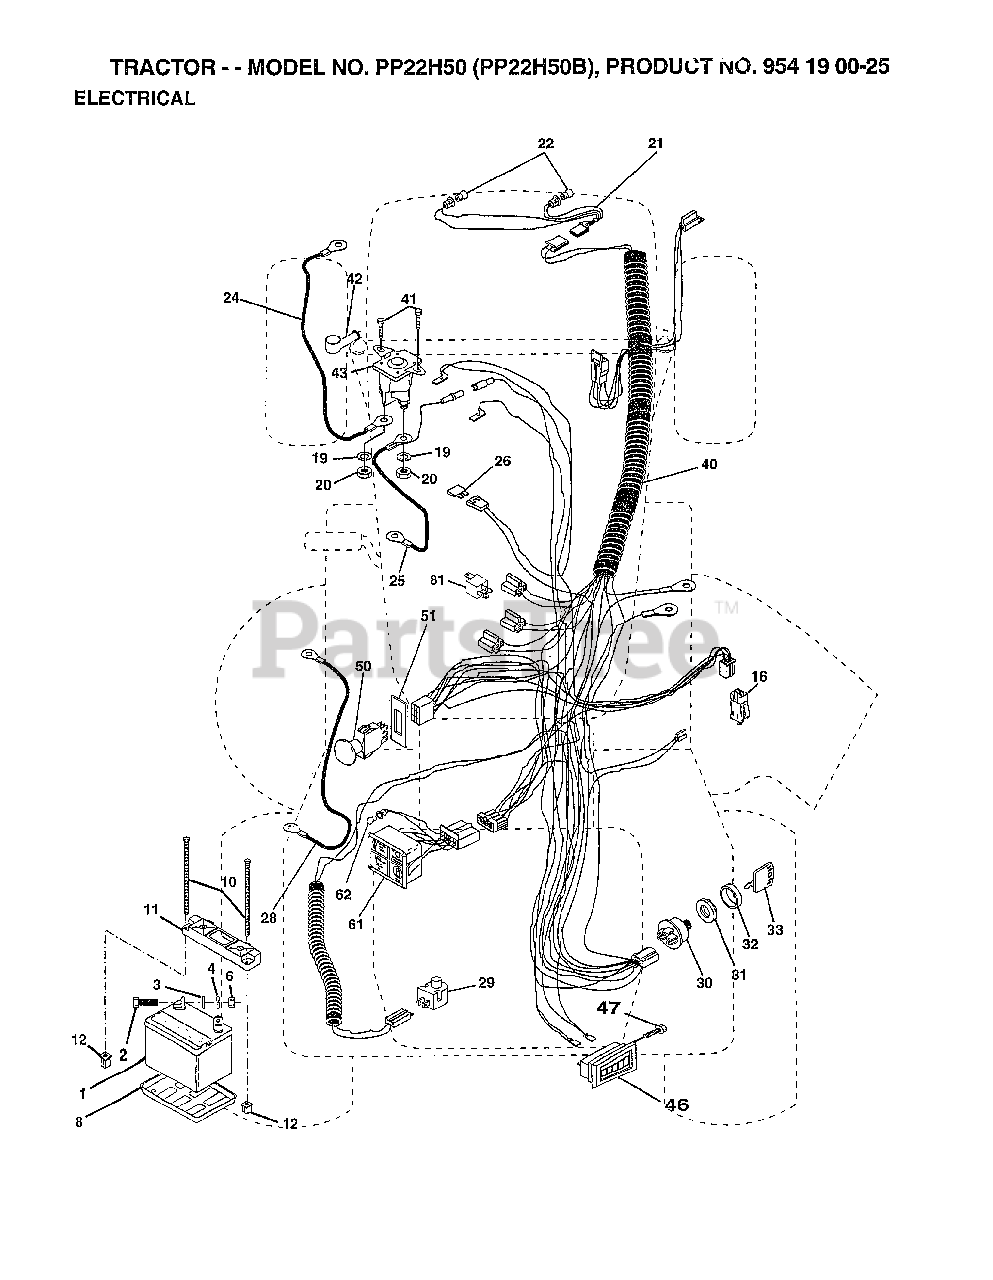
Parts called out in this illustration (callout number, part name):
3	LOCKWASHER
4	WASHER
8	"TRAY T, BATTERY"
11	HOLDDOWN BATTERY
16	SWITCH INTERLOCK
20	NUT
21	"HARNESS,LIGHT SOC"
22	HEADLAMP BULB
24	CABLE.BATY.22.RED
25	CABLE.BATRY.4GA.
26	FUSE HYT
28	"CABLE BATTERY,GRD"
29	SWITCH.PLUNGER
30	SWITCH IGN 4POS
31	NUT IGNITION
32	COVER KEY SWITCH
33	KEY
40	HARNESS.IGNITION
41	SCREW
46	HOUR METER T
47	SCREW
50	PTO SWITCH.BLK
51	RING RETAIN PTO
61	LIGHT.PKG.ASM.
62	BULB LIGHT T
81	RELAY ASSY T
